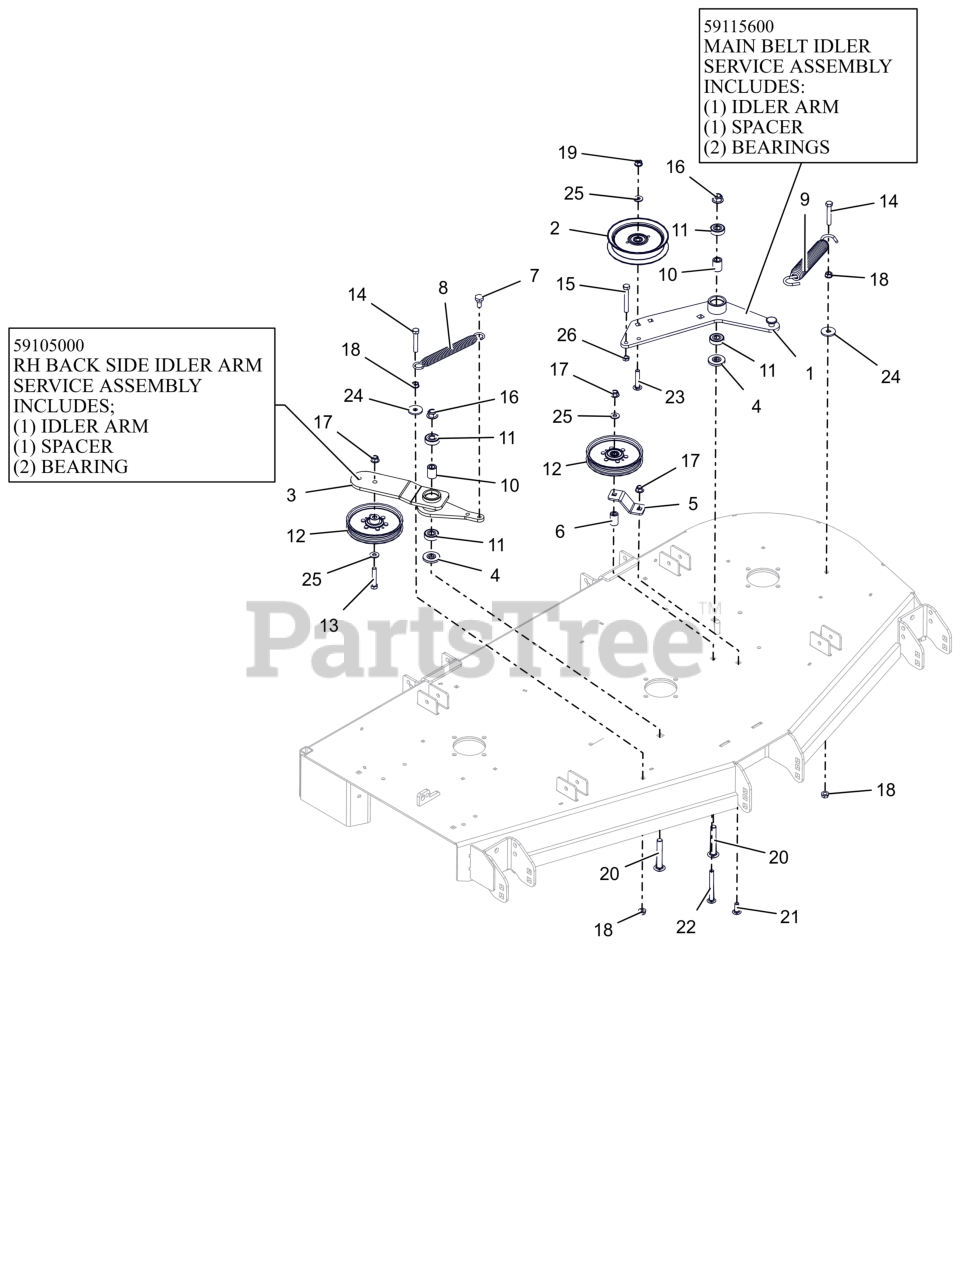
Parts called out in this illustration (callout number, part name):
1	WLDMT, DECK PTO IDLR ARM
1	ASSEMBLY, MAIN BELT IDLER
2	IDLER, FLAT 5.00"
3	WLDMT, DECK RH IDLER ARM
3	RH BACKSIDE IDLER ARM ASSEMBLY
4	SPACER, IDLER ARM
5	PTO FIXED IDLER MTG BRKT -RED
6	BUSHING, SLV .380X.750X1.190
7	BLT,SHLDR EP .38-16X.30 HEX YZ
8	SPRING, EXTENSION
9	SPRING, EXTENSION
10	SPACER .510 X .75 X 1.1485
11	BRG-BALL .500X1.38X.437
12	PULLEY, FLAT IDLER
13	BLT,HEX .38-16X2.00 G5 ZCC
14	BLT,HEX .38-16X2.25 G5 ZCC
15	BLT, HEX .38-16X2.75 G5 ZCC
16	NUT,NYL-FLG .50-13 GF ZCC
17	NUT,NYL-FLG .38-16 GF ZCC
18	NUT, SPNLK-FLG .38-16 G5 ZCC
19	NUT-LK-CTR-FLG .375-16 GF ZCC
20	BTL,RHSSN .500-13 X 3.25 G5 ZCC
21	BLT,RHSSN .38-16X1.00 G5 ZCC
22	BLT,RHSSN .38-16X3.50 G5 ZCC
23	BLT,RHSSN.375-16X2.00 G5 ZCC
24	WSHR,FLT .406X1.375X.135 ZCC
25	WSHR,FLT .375X.875X.083 ZCC
26	NUT-JAM .375-16 G2 ZCC
